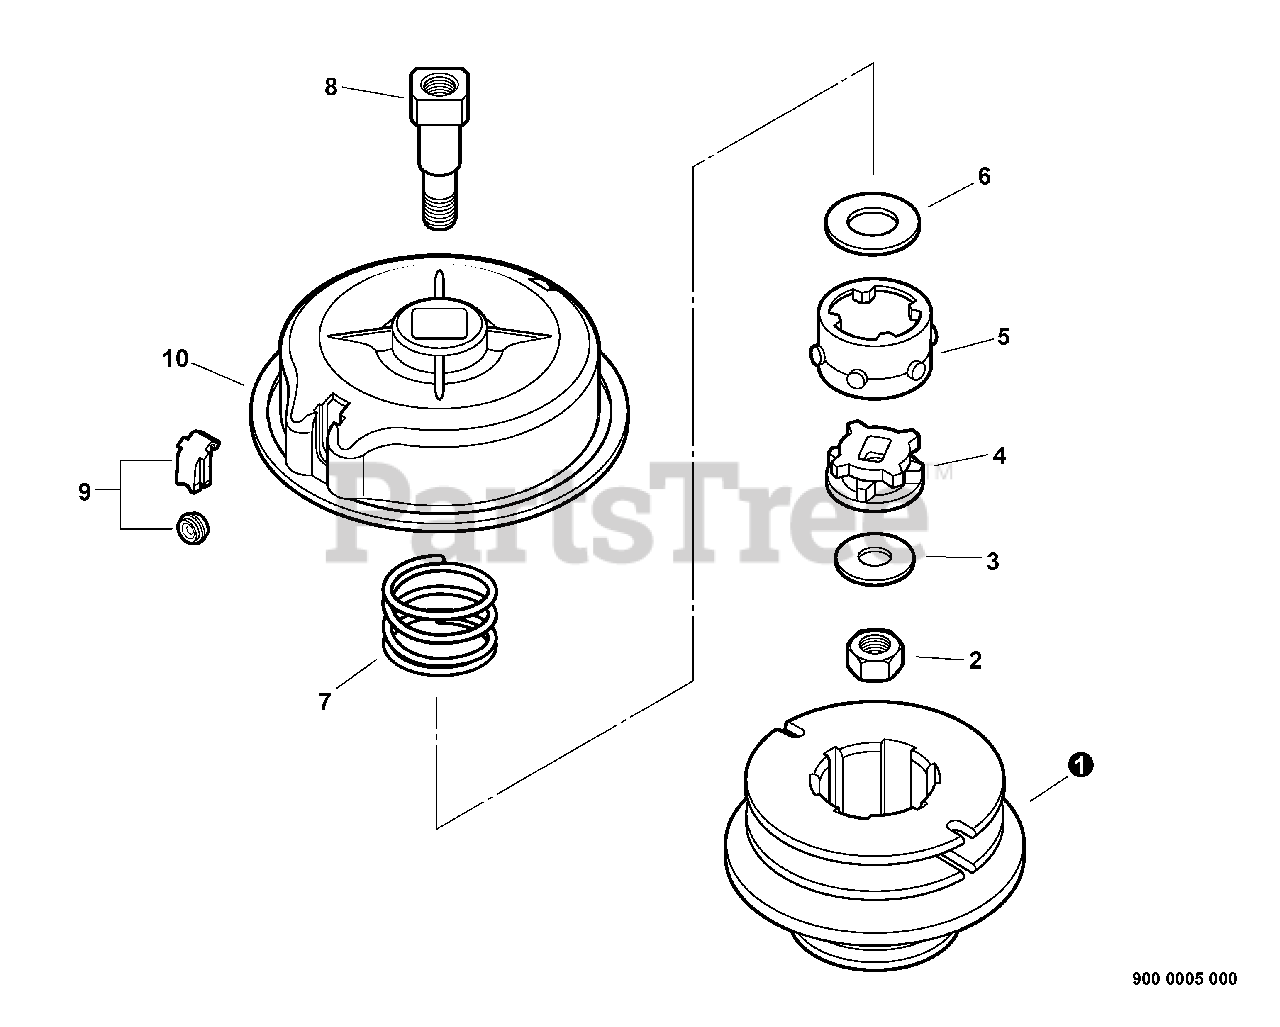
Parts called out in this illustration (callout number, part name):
2	NUT, LOCK
3	WASHER, FLAT
4	CAM, INNER
5	CAM, OUTER
6	WASHER, FLAT
8	BOLT, SHAFT 10 MM
9	REPLACEMENT KIT
10	HOUSING
